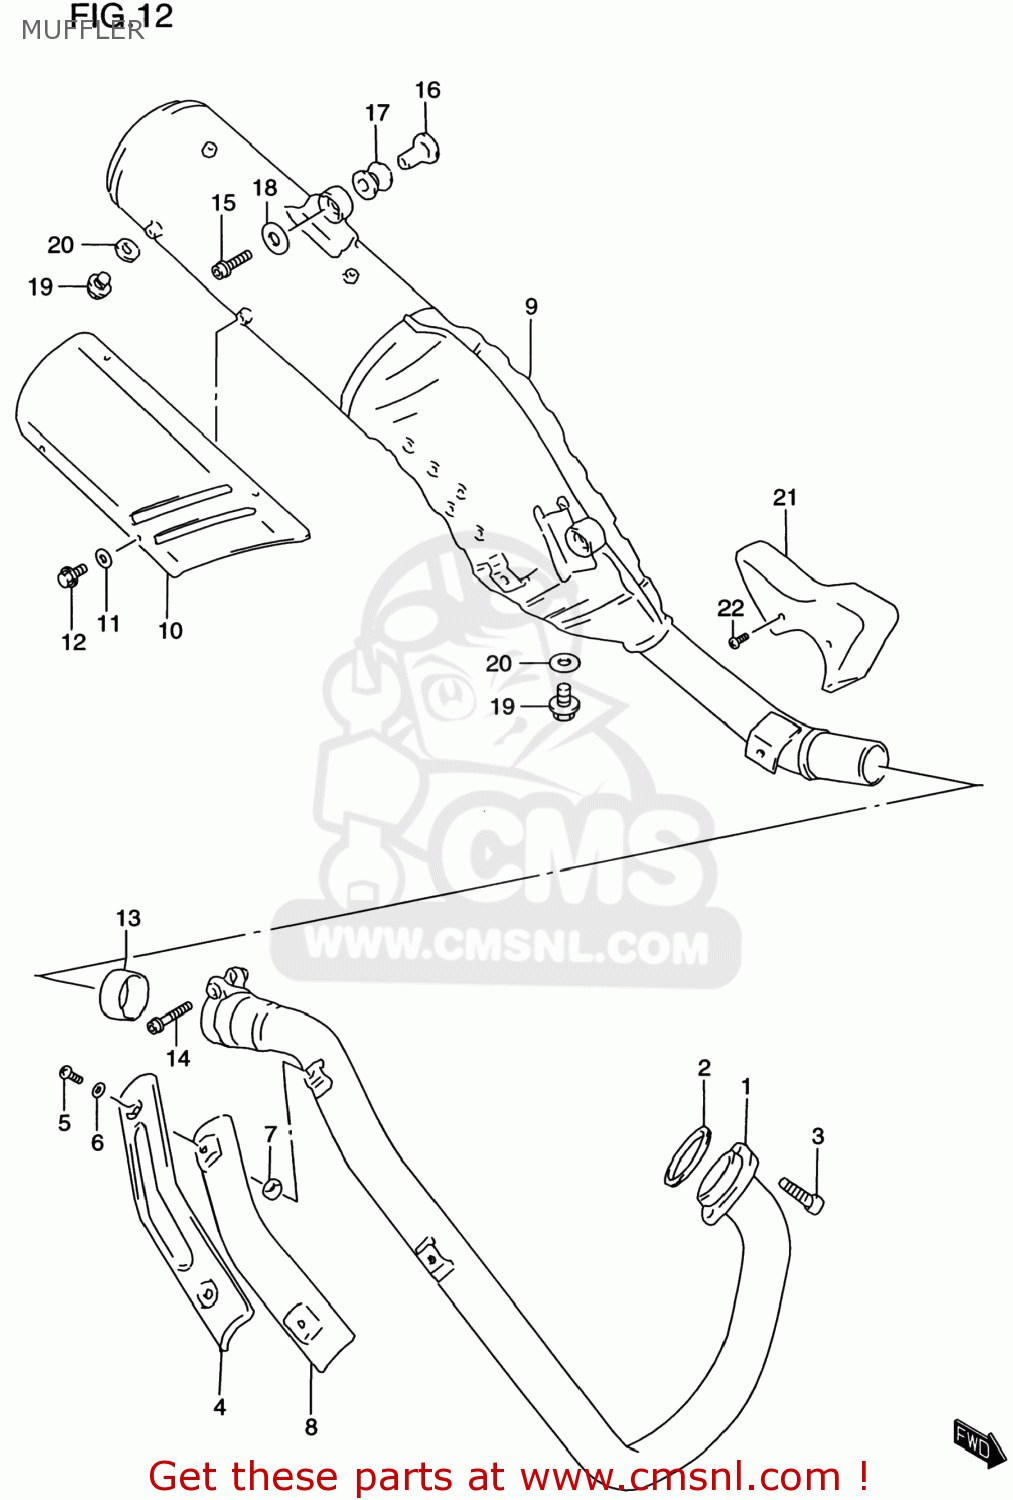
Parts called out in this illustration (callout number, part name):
1	PIPE COMP,EXHAUST
2	GASKET,EXHAUST PIPE (NAS)
3	BOLT
4	COVER,EXHAUST PIPE
5	SCREW(6X12)
6	WASHER(6.5X13X1.0)
7	GASKET(6X16X1.4) (NAS)
8	COVER,EXHAUST PIPE INNER
9	BODY,MUFFLER
10	COVER,MUFFLER
11	WASHER(6.5X13X1.0)
12	SCREW(6X10)
13	CONNECTOR,MUFFLER
14	BOLT
15	BOLT(8X30)
16	SPACER(8.6X12X17.5)
17	CUSHION
18	WASHER(8.5X28X1.6)
19	PLUG(12X9)
20	GASKET(12.1X16.2X3.7) (NAS)
21	COVER,CONNECTOR CLAMP
22	SCREW(6X10)
